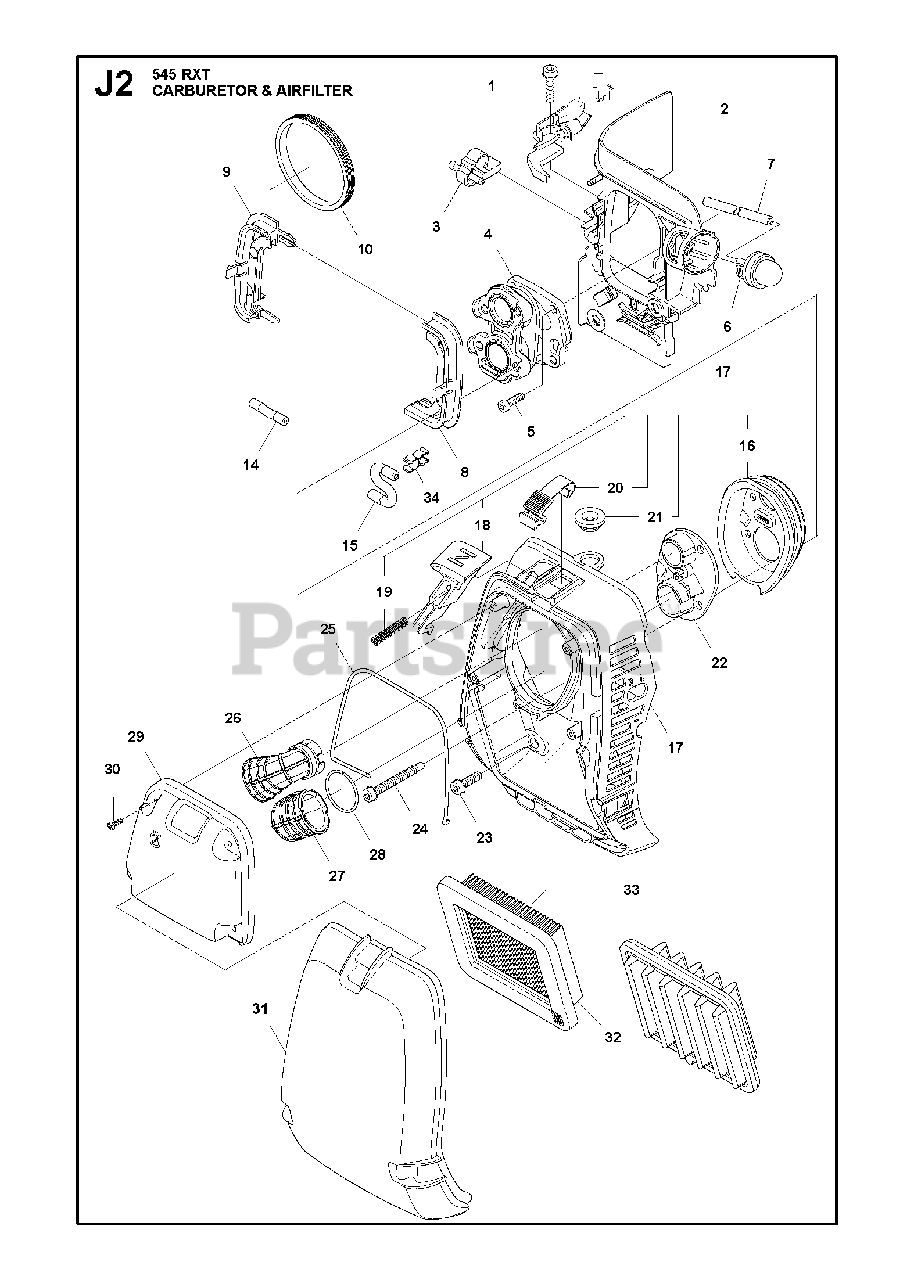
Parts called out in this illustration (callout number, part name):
2	INSULATION WALL
4	INLET PIPE
6	AIR PURGE BUBBLE
10	SEALING RING
14	SUCTION HOSE
16	SEALING
17	FILTER HOLDER ASSY
18	CHOKE CONTROL
19	SPRING
20	HOLDER
21	GROMMET
22	COVER PLATE
23	SCREW IHSCFM
26	INLET PIPE AIR HEAD
27	INLET PIPE ASSY
28	LOCKING SPRING
29	COVER LID ASSY
31	FILTER COVER
32	FILTER AIR FILTER PAPER
